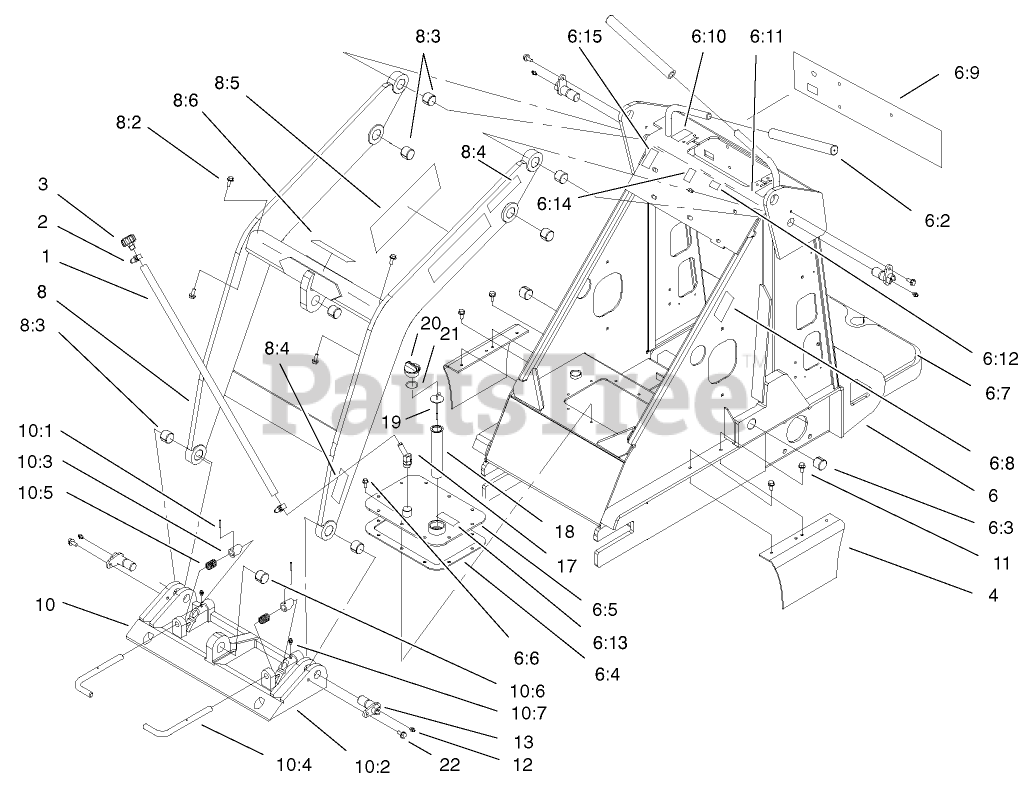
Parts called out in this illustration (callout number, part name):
1	HOSE-VENT
2	CLAMP-HOSE
3	BREATHER
4	Cover-Chain
6	FRAME ASM
6:2	GRIP-CUSHION
6:3	BUSHING-TENSION
6:4	GASKET-COVER
6:5	COVER
6:6	SCREW
6:7	TREAD-FOOT
6:8	DECAL-WARNING, KEEP HANDS AWAY
6:9	DECAL-PANEL, INSTRUMENT
6:10	DECAL-CHOKE
6:11	DECAL-THROTTLE
6:12	DECAL-LIMITER, SPEED
6:13	DECAL-ONLY, HYD OIL
6:14	DECAL-SELECTOR
6:15	DECAL-POWER, AUXILIARY
8	Loader ASM
8:2	SCREW-HWHTF
8:3	BUSHING-TENSION
8:4	DECAL-WARNING, KEEP HANDS AWAY
8:5	DECAL-DANGER
8:6	DECAL-CAUTION
10	QUICK ATTACH ASM
10:1	PIN-SPECIAL
10:2	Mount-Quick Attach
10:3	CAM-ATTACH, QUICK
10:4	Pin-Quick Attach
10:5	SPRING-COMPRESSION
10:6	BUSHING-TENSION
10:7	FITTING-GREASE
11	SCREW-HWHTF
12	FITTING-GREASE
13	PIN-PIVOT
17	FITTING-HYD, 45 DEG
18	FILTER-SCREEN
19	DIPSTICK
20	PLUG-PLASTIC
21	O-RING
22	BOLT-SHOULDER
